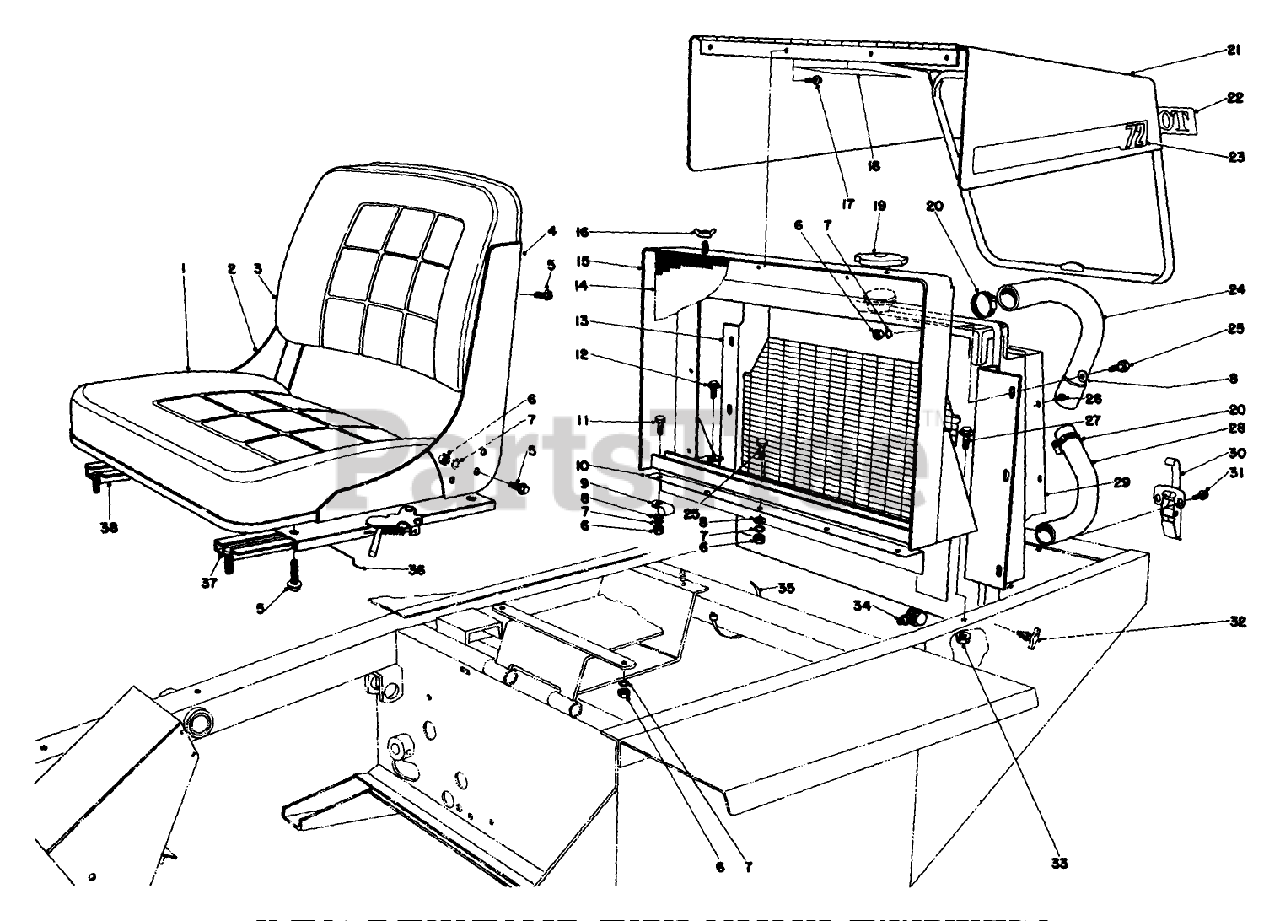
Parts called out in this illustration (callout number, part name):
1	Seat Cushion
2	RH RAIL
3	Backrest
4	LH RAIL
5	SCREW-HHF
6	NUT-HEX
7	WASHER-LOCK
8	WASHER-PLAIN
9	CLAMP-R
10	Sealing Plate Grill
11	SCREW-HH
12	SCREW-HWHTF
13	RADIATOR ASM
14	GRILLE WA R
15	Radiator Support
16	NUT-WING
17	SCREW-HWH
18	Decal
19	RAD PRESS CAP ASM
20	CLAMP-HOSE
21	Hood
22	Decal
23	DECAL
24	UPPER HOSE
25	SCREW-HH
26	SCREW-THD FRM,HWH
27	SCREW-HHF
28	LOWER HOSE
29	Radiator Shroud
30	CLAMP-SLOTTED
31	10-24 X 1/2 SEMS SCR
32	DRAINCOCK
33	NUT-HF
34	ELBOW
35	TIE-CABLE
36	Connecting Rod
37	Adjuster L.H.
38	Adjuster R.H.
